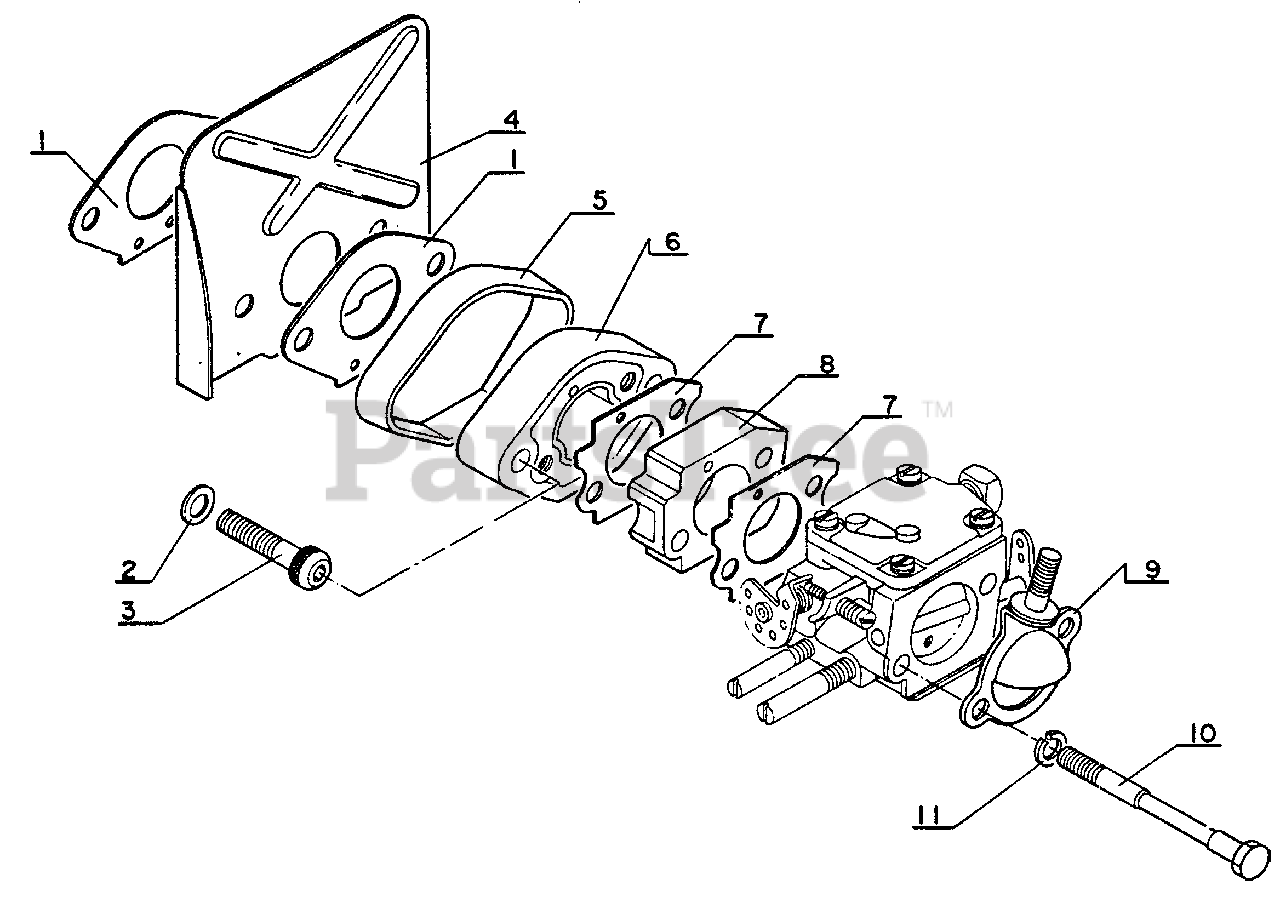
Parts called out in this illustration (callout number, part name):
1	GASKET, INTAKE
3	BOLT - 6X28
4	SHIELD, INTAKE
5	SEAL, DUST
6	CASE, CARBURETOR
7	GASKET, INTAKE
8	INSULATOR, INTAKE
9	PLATE, PREVENT
11	LOCKWASHER - 5
